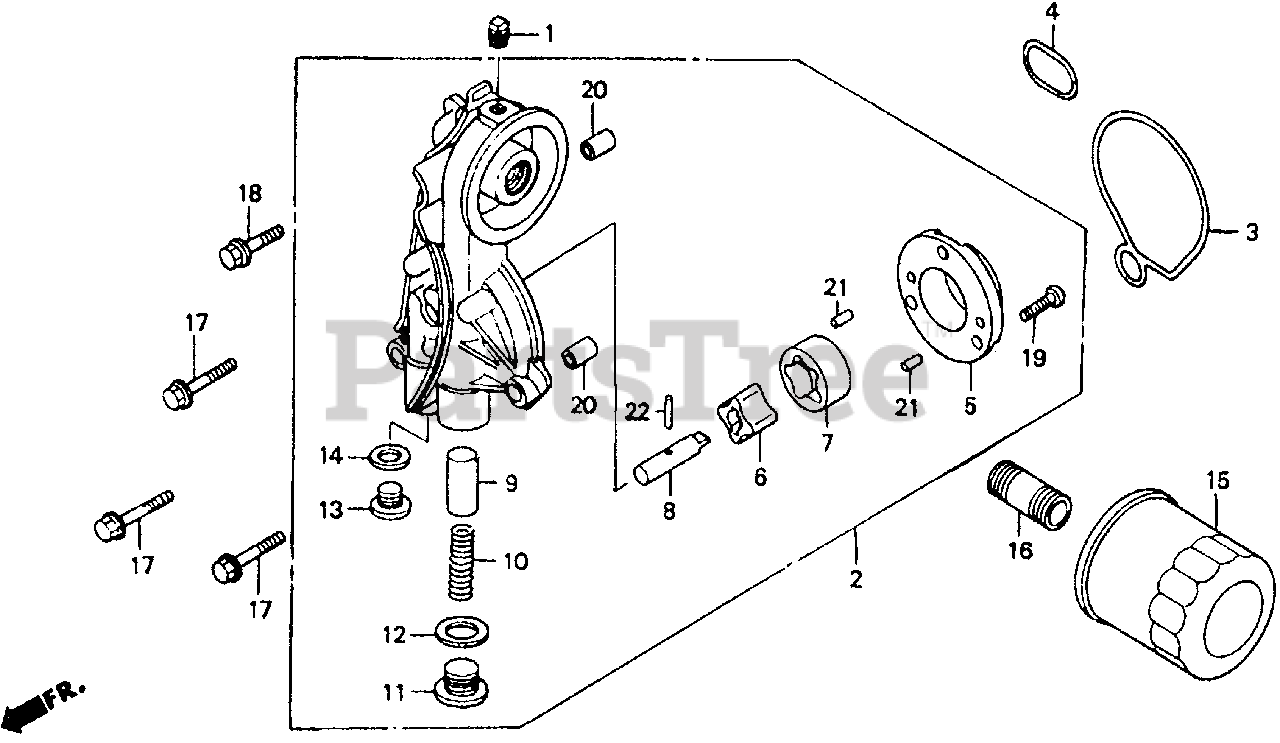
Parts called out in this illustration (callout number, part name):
1	BOLT, SEALING
2	PUMP ASSY., OIL
3	GASKET, OIL PUMP
4	GASKET, OIL PUMP (B)
5	COVER, OIL PUMP
6	ROTOR, OIL PUMP (INNER)
7	ROTOR, OIL PUMP (OUTER)
8	SHAFT, OIL PUMP
9	VALVE, RELIEF
10	SPRING, RELIEF VALVE
11	BOLT, SEALING (18MM)
12	WASHER, SEALING (18MM)
13	BOLT, SEALING (14MM)
14	WASHER, SEALING (14MM)
15	FILTER, OIL
15	FILTER, OIL (DENSO)
15	FILTER, OIL (TOYO ROKI)
16	HOLDER, OIL FILTER
17	BOLT, FLANGE (6X32)
18	BOLT, FLANGE (6X25)
19	SCREW, PAN (6X14)
20	PIN A, DOWEL (8X14)
21	PIN, DOWEL (5X8)
22	ROLLER (3X15.8)
